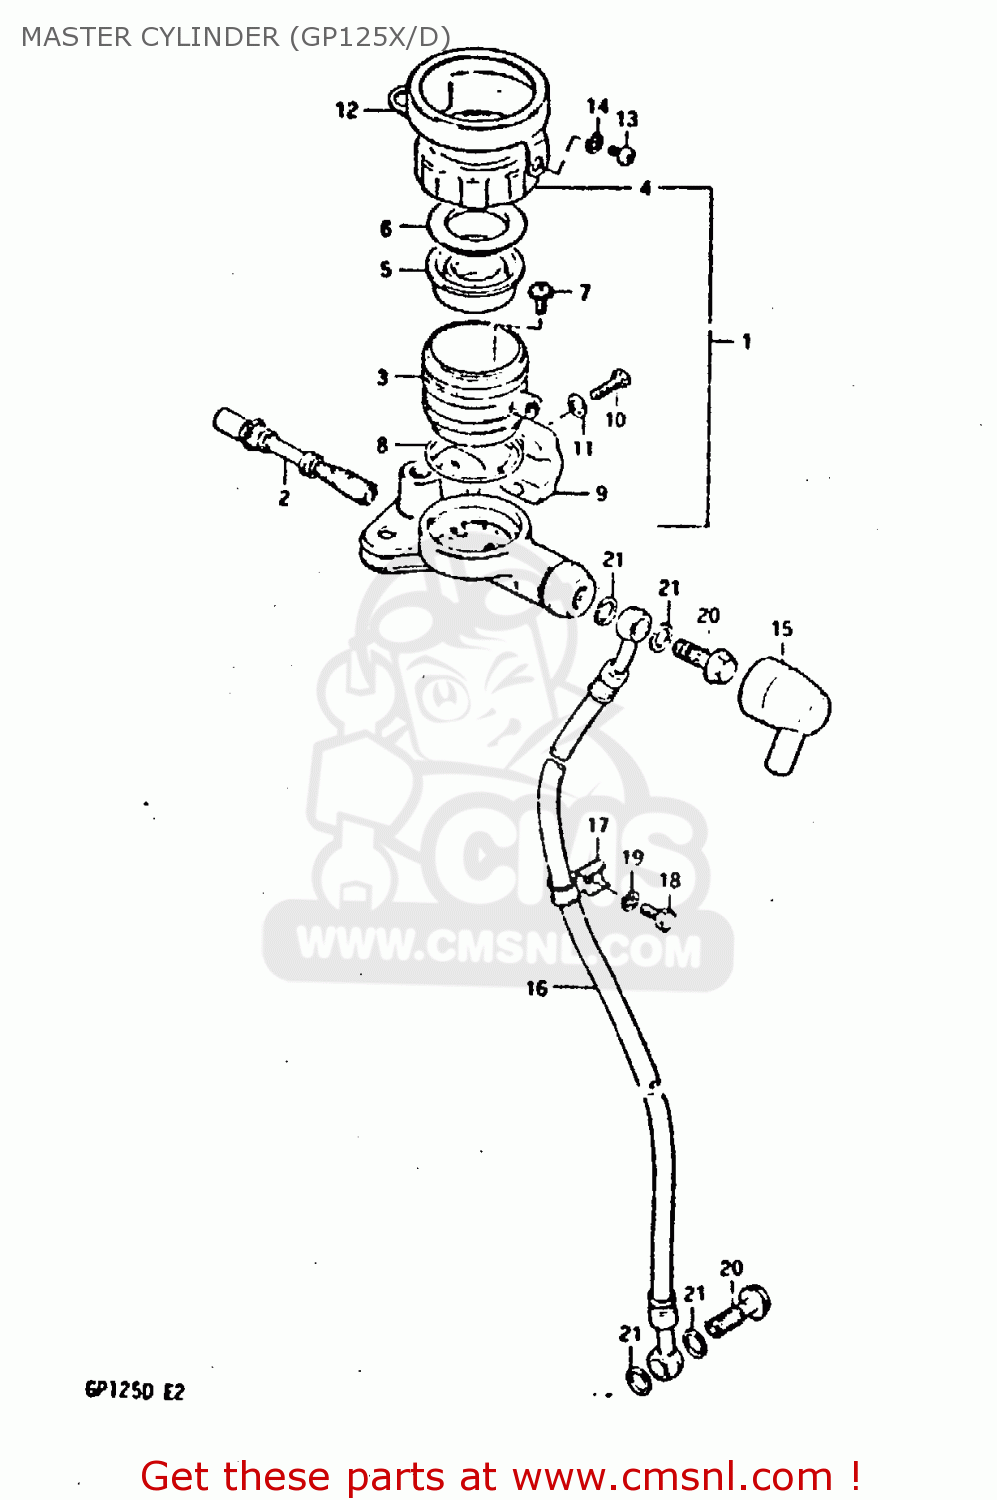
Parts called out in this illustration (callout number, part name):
1	CYLINDER ASSY, MASTER
2	PISTON & CUP SET
3	RESERVOIR
4	CAP
5	DIAPHRAGM
6	PLATE,DIAPHRAGM
7	SCREW,MASTER CYLINDER
8	O RING
9	HOLDER,MASTER CYLINDER
10	BOLT
11	WASHER
12	LOCK PLATE, CAP
13	SCREW
14	LOCK WASHER
15	BOOT,MASTER CYLINDER
16	HOSE, BRAKE
17	CLAMP,BRAKE HOSE
18	BOLT
19	LOCK WASHER
20	BOLT,UNION
21	WASHER
